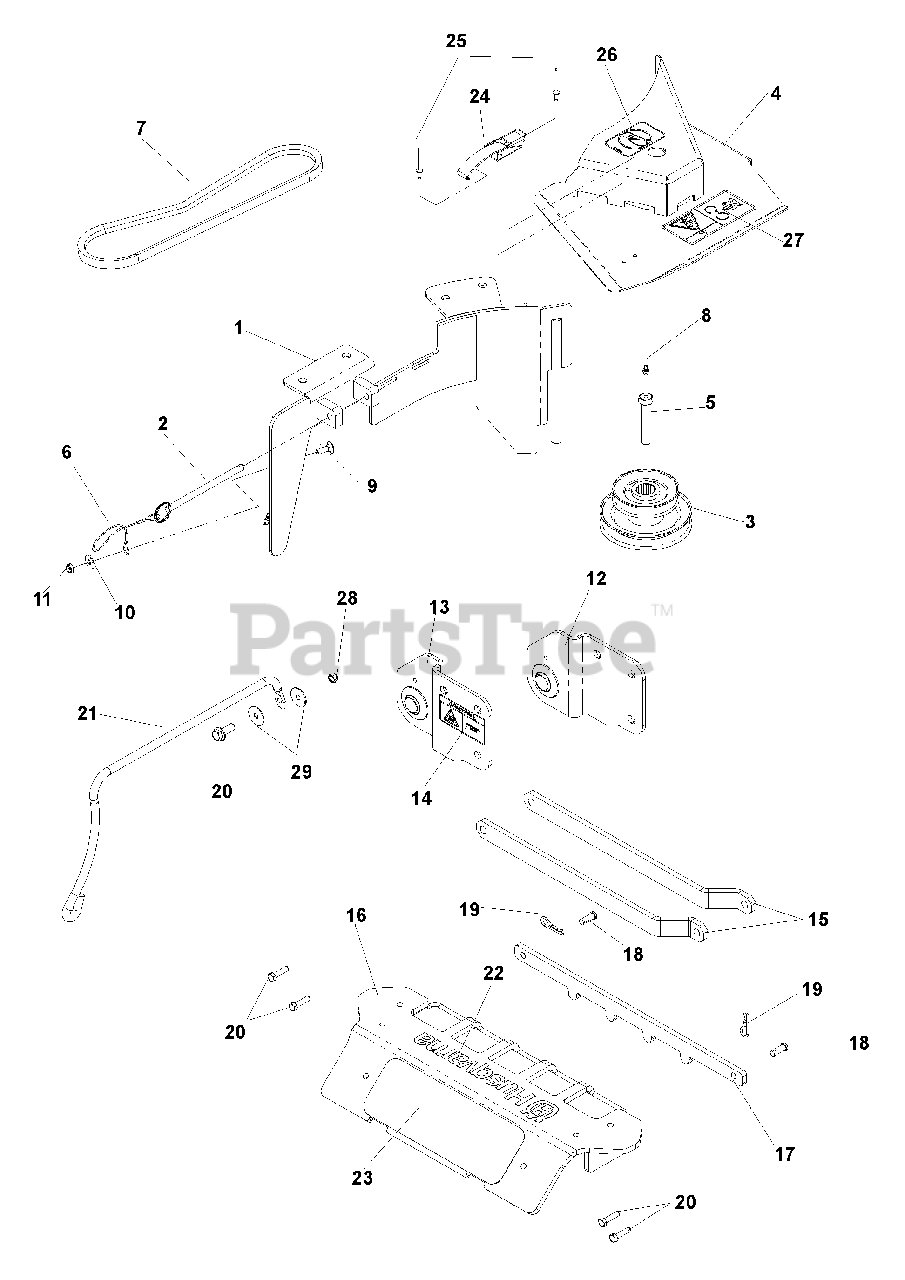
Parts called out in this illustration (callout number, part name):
1	BLOWER DECK PLATE, 48" DECK
1	BLOWER DECK PLATE, 52" DECK
1	BLOWER DECK PLATE, 61" DECK
3	STACK PULLEY, 48" DECK
3	STACK PULLEY, 52" DECK
3	STACK PULLEY, 61" DECK
4	BELT SHIELD, 48" DECK
4	BELT SHIELD, 52" DECK
4	BELT SHIELD, 61" DECK
5	HCS, 7/16-20 X 2 1/2, GR8
7	BELT, 48" DECK
7	BELT, 52" DECK
7	BELT, 61" DECK
8	ZERK
9	RHSNB, 1/4-20 X 3/4, GR2
10	WASHER, 1/4
11	NUT, 1/4-20, JAM, NYLOC
12	HITCH BRACKET, LEFT
13	HITCH BRACKET, RIGHT
14	DECAL, HOT SURFACE
16	WEIGHT BAR
17	HOLD DOWN, WEIGHT BAR
18	CLEVIS PIN
19	SPRING RETAINER
20	HCS, 5/16-18 X 1 1/4, GR5
21	HOSE SUPPORT
22	DECAL, HUSQVARNA
23	ABRASIVE PAD
24	DRAW LATCH
25	RIVET, BLIND, 5/32 DIA.
26	DECAL, NO STEP
27	DECAL, DANGER BELT DRIVES
28	NUT, 5/16-18, NYLOC
29	WASHER, 5/16
